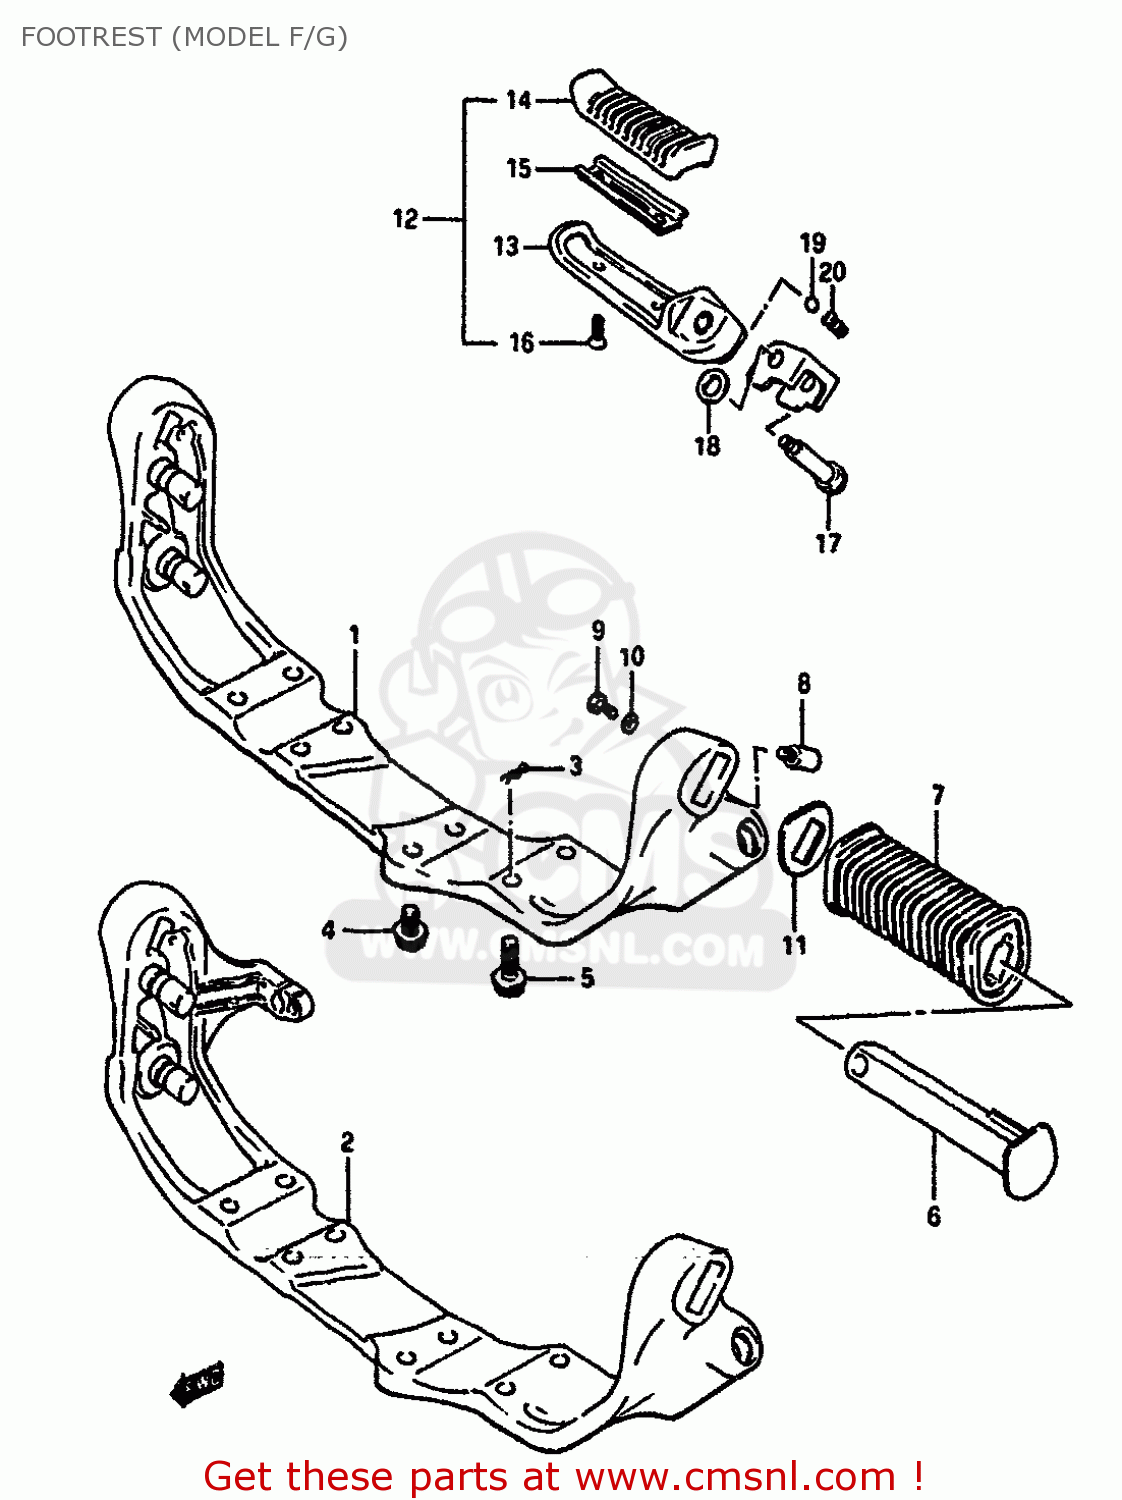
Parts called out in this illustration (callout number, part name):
1	BRACKET,FRONT FOOTREST
2	BRACKET,FRONT FOOTREST
3	PIN,SNAP
4	BOLT
5	BOLT(8X25)
6	BAR,FR FOOTREST,R
7	RUBBER,FR FOOTREST
8	BOLT,FRONT FOOTREST RUBBER
9	BOLT 5X12
10	LOCK WASHER
11	WASHER,FR FOOTREST,R
12	FOOTREST ASSEMBLY,REAR
13	BAR COMP,PILLION FOOTREST
14	RUBBER,PILLION FOOTREST
15	PLATE,RUBBER STOPPER
16	SCREW 5X16
17	BOLT(6X34.5)
18	SHIM
19	BALL
20	SPRING
